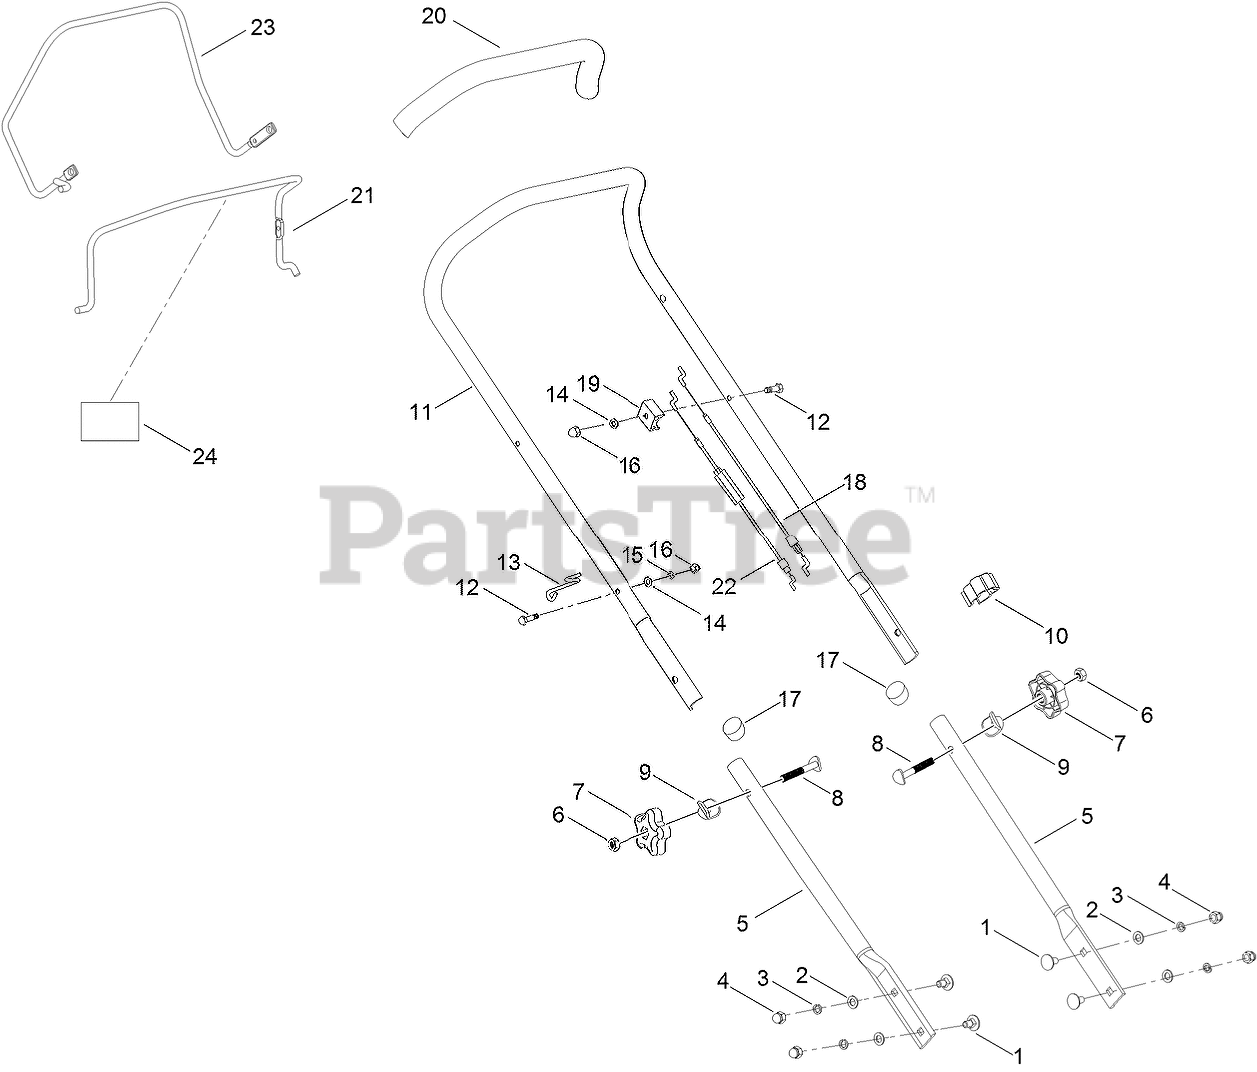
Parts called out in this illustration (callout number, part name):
2	WASHER
3	WASHER-SPRING
4	NUT-LID
5	HANDLEBAR-LOWER
6	NUT-HEX
7	KNOB-ROTARY
8	BOLT-FLAT HEAD
9	WASHER-CURVE
10	CABLE CLAMP
11	HANDLEBAR-UPPER
12	BOLT-HH, FLANGE
13	HOOK-CABLE
14	WASHER-PLAIN
15	WASHER-SPRING
16	NUT-LID
17	PLUG-TUBE
18	CABLE-BLOCK, FIXED
19	CABLE-BLOCK, FIXED
20	GRIP-HANDLE
21	LEVER-ENGINE
22	CABLE-CLUTCH
23	LEVER-CLUTCH, GEARBOX
24	DECAL-STOP
